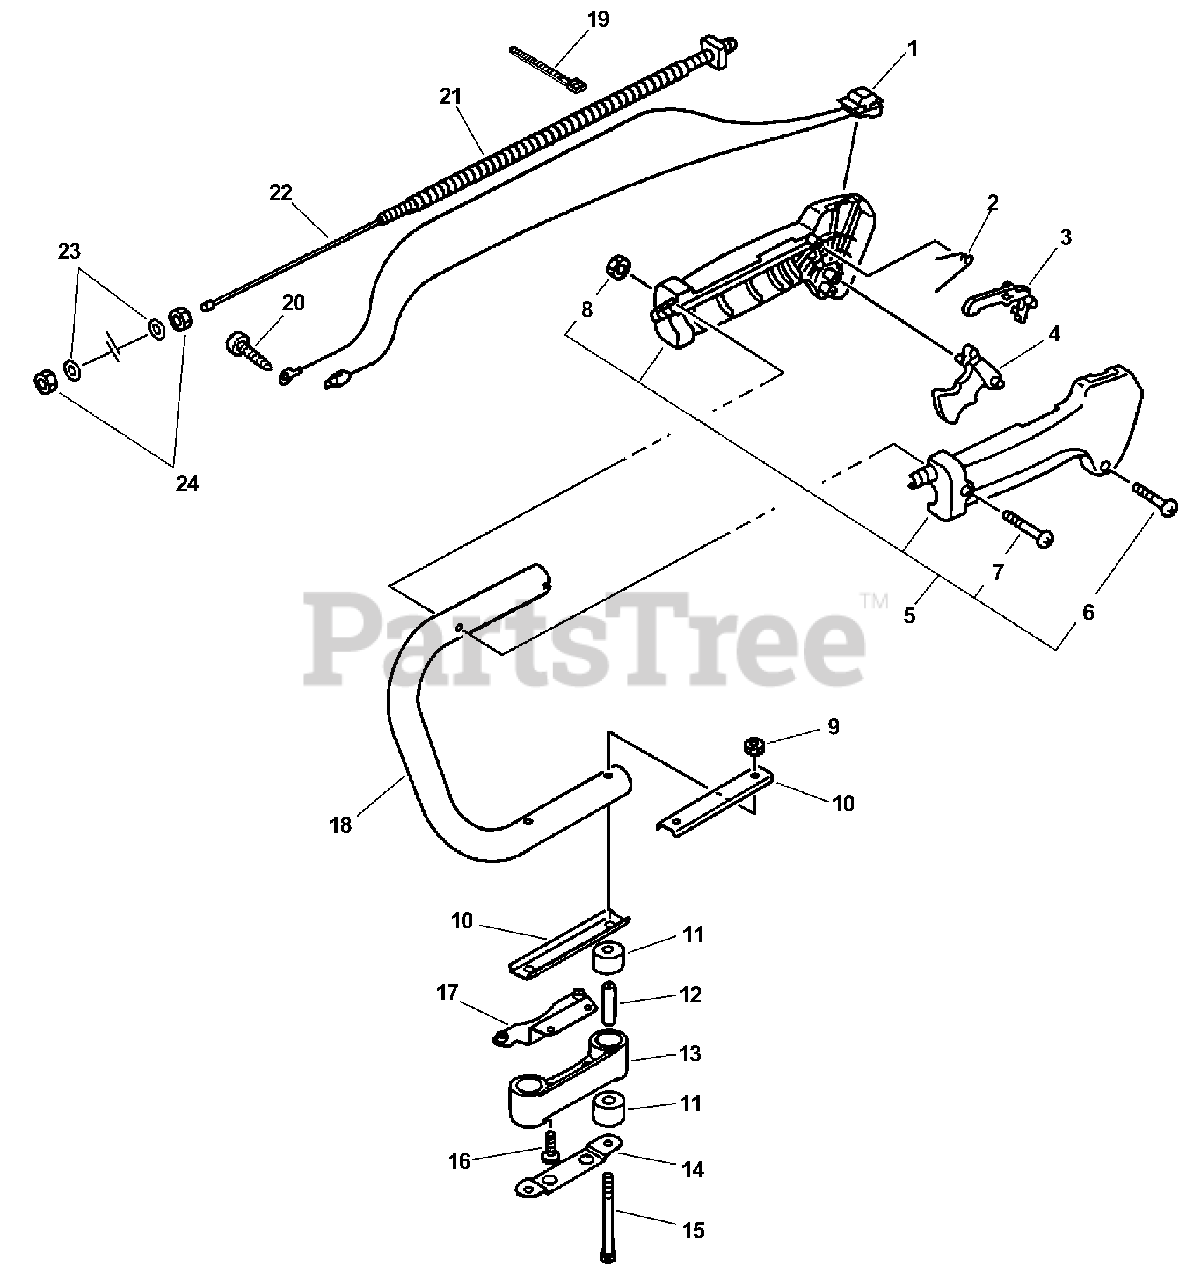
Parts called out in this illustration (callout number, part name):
1	IGNITION SWITCH ASSY
2	SPRING, TORSION
3	LOCKOUT, THROTTLE
4	TRIGGER, THROTTLE
5	CONTROL HANDLE KIT
6	SCREW 3×25
7	SCREW 5×30
8	NUT M5
9	NUT, LOCK M5
12	SPACER
13	BRACKET, HANDLE
15	BOLT 5×60
16	SCREW 5×16
18	HANDLE, REAR
19	TIE, CABLE
20	SCREW 5×10
22	CABLE, THROTTLE
23	WASHER 6.5×11.5×0.8
